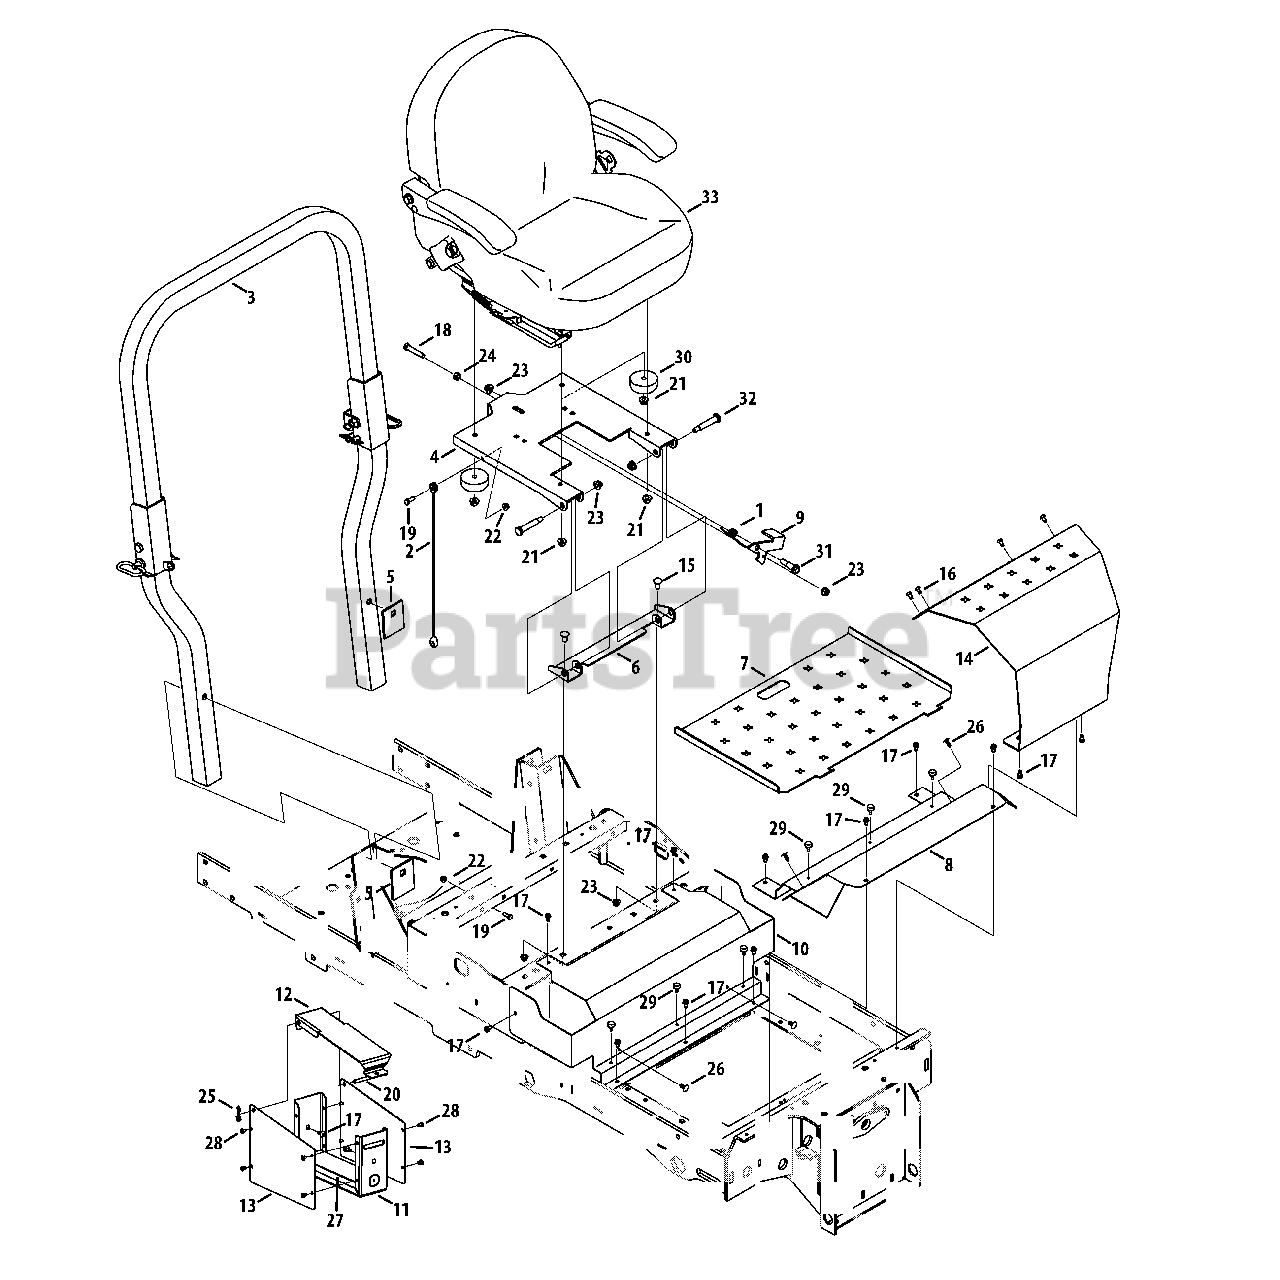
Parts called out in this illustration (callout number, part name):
1	Torsion Spring, .725 x 1.0 x .09
2	Cable Support
3	Folding ROPS Assembly
5	Deck Reinforcement Plate
6	Seat Mounting Bracket
7	Floor Panel Tray
8	Floor Panel
9	Seat Lever Latch
10	Control Panel Cover
12	Storage Box Lid
13	Storage Box Side Panel
14	Front Panel Cover
15	Carriage Bolt, 3/8-16 x .75
16	Screw, 1/4-20 x .5
17	Hex Flange Screw, 1/4-20 x .500
18	Hex Cap Screw, 3/8-16 x 2.25
19	Hex Cap Screw, 1/4-20 x .75
20	Clevis Pin, .25 x 3.5
21	Nut, 5/16-18, Flangelock
22	Nut, 1/4-20, Flangelock
23	Nut, 3/8-16, Flangelock
24	Nut, 3/8-16, Hex
25	Cotter Pin, Bow Tie
26	Clip, .250 Dia.
27	Adhesive Pad
28	Rivet, 3/16 x .325
29	Bumper, .62 Dia. x .3
30	Rubber Bumper, 2.5 x 1.0
31	Shoulder Bolt, .50 x .925, 3/8-16
32	Shoulder Bolt, .500 x 2.23, 3/8-16
